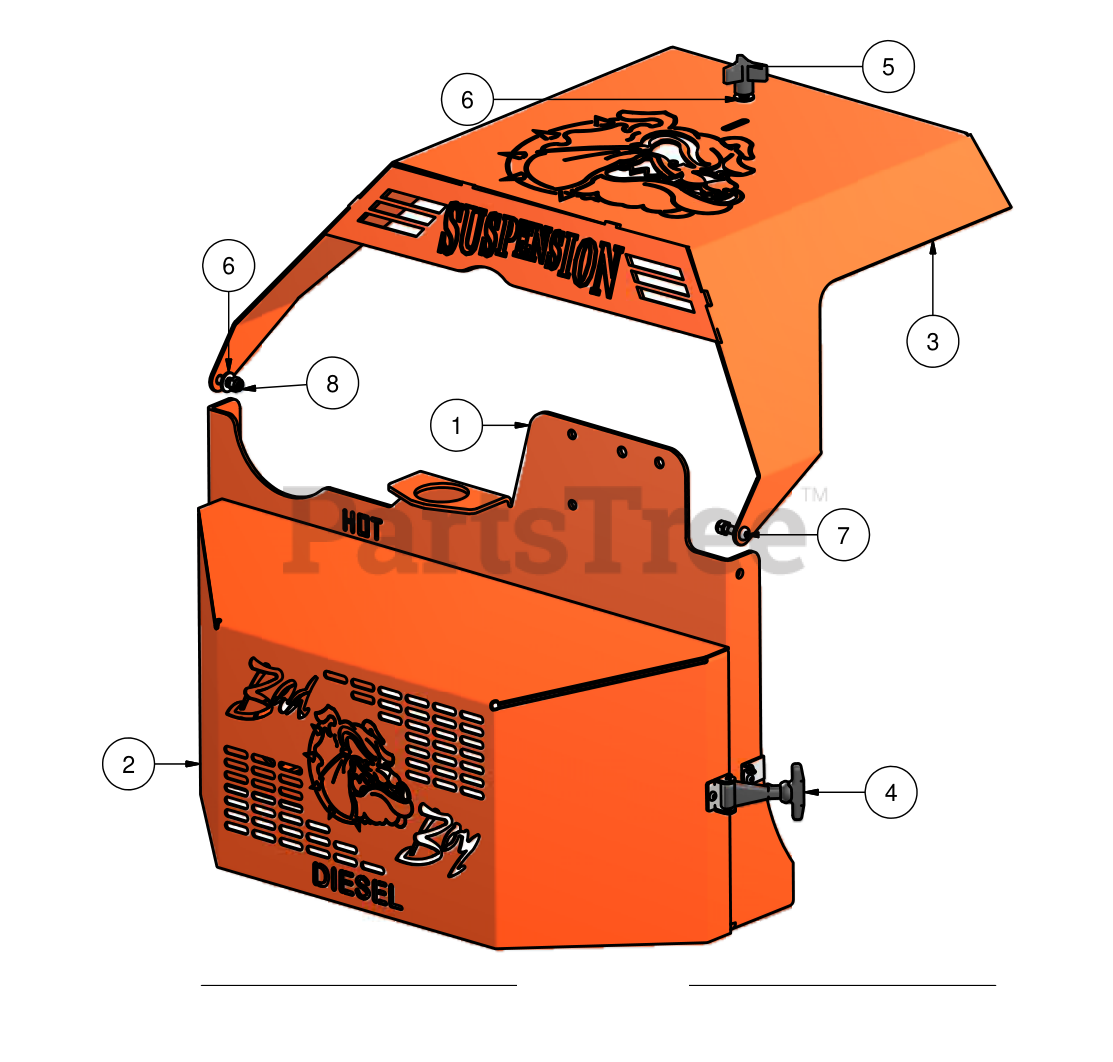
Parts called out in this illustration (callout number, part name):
1	Diesel Pump Plate
2	Back Pump Cover- Diesel
3	Diesel Hood
4	Pump Latch Cover
5	5/16" Knob
6	.360 ID Plastic Washer
7	5/16" x 3/4" Bolt
8	5/16" Nylock Nut
